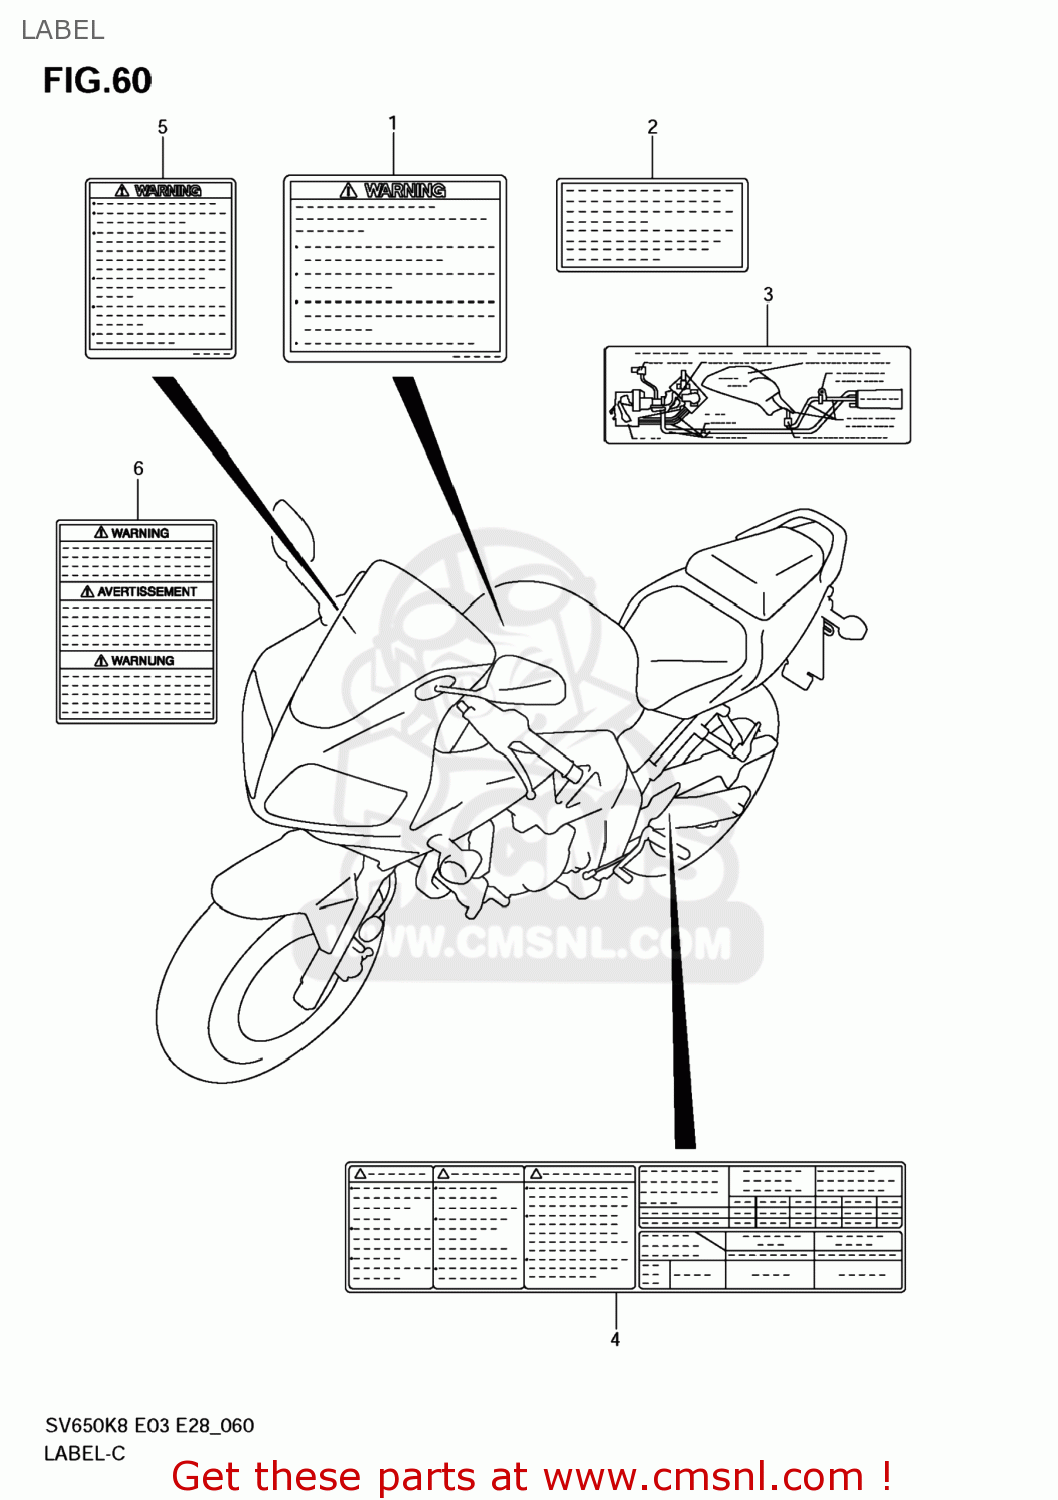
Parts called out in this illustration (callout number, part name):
1	LABEL,GENERAL WARNING
2	LABEL,MANUAL NOTICE
3	LABEL, ROUTING E33
4	LABEL,TIRE INFORMATION
5	LABEL,SCREEN
6	LABEL,WARNING STEERING
7	MANUAL,OWNER'S
